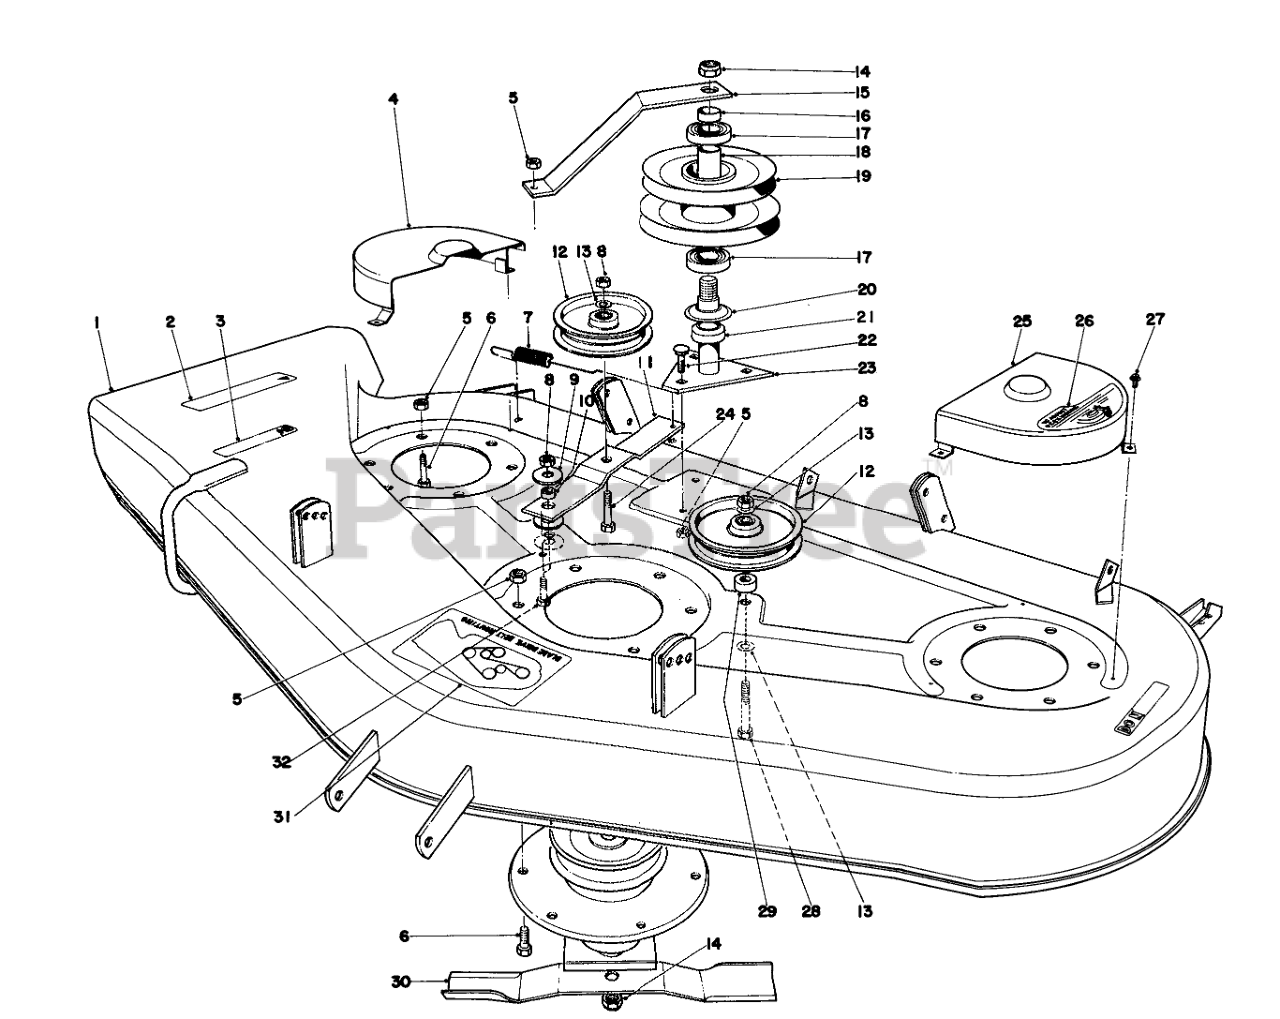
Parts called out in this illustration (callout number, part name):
2	CAUTION DECAL
3	DECAL-NO STEP
4	RH BELT COVER WA B
5	NUT-LOCK, CONE
6	SCREW-HH
7	EXT SPRING O
8	NUT-LOCK, CONE
9	WASHER
10	IDLER BRKT SPACER
11	Idler Pulley Bracket
12	PULLEY-IDLER
13	WASHER-FLAT
14	NUT-LOCK, NI
15	Support Spindle
16	SPACER
17	BEARING
18	SPACER
19	Pulley & Bearing Assembly
20	DUST COVER
21	SPACER
22	BOLT-CARR
23	SHAFT SADDLE ASM
24	SCREW-HH
25	LH BELT COVER WA B
26	WHEEL ADJ DECAL
27	SCREW-HWHTF
28	SCREW-HH
29	SPACER O
30	Blade
31	Decal Belt Routing
32	SCREW-HH
